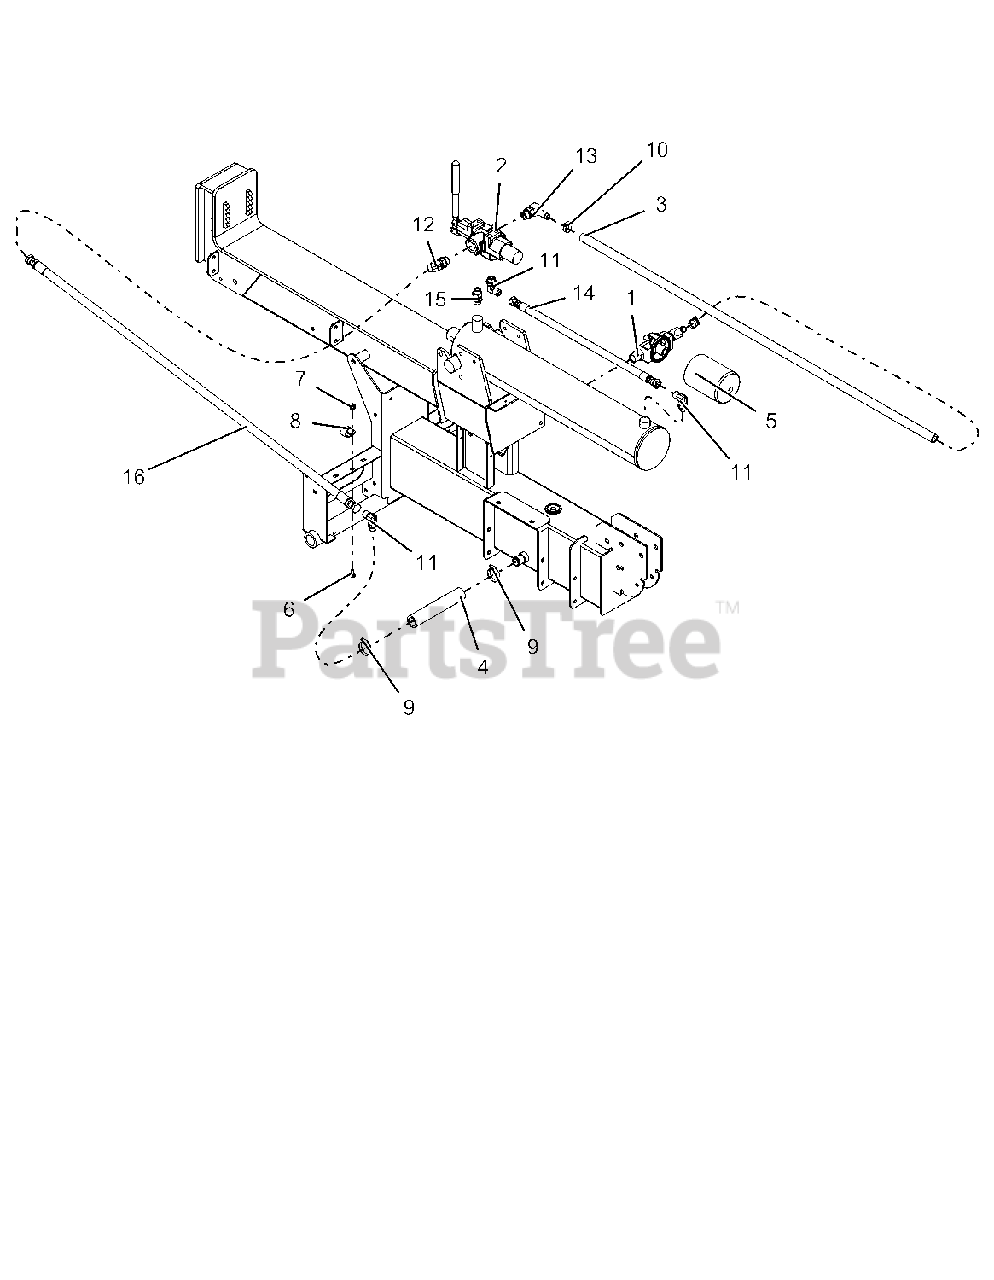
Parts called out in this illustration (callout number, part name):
1	ASM, FILTER HEAD
2	VALVE CONTROL-SPLITTER
3	HOSE,HYD RETURN 10LOLA X 53"
4	HOSE, HYD - SUCTION 7.375"
5	FILTER,HYDRAULIC OIL-NO BYPASS
6	@BLT-RDHDSQNK .31-18X.75 G5YZ
7	@NUT-LK-TOP-FLG .31-18 YWZC
8	CLAMP, COUSHIONED STEEL REV
9	CLAMP-HOSE 1.50X.81X1.42
10	CLAMP,.88 DIA. HOSE
11	FTG,HYD 6801-8-8
12	FTG,HYD 6802-8-10
13	FTG,HYD 4601-10-10
14	HOSE, HYD - 22"
15	FTG, HYD - STR 08MAORB-08MORB
16	HOSE, HYD - 58"
